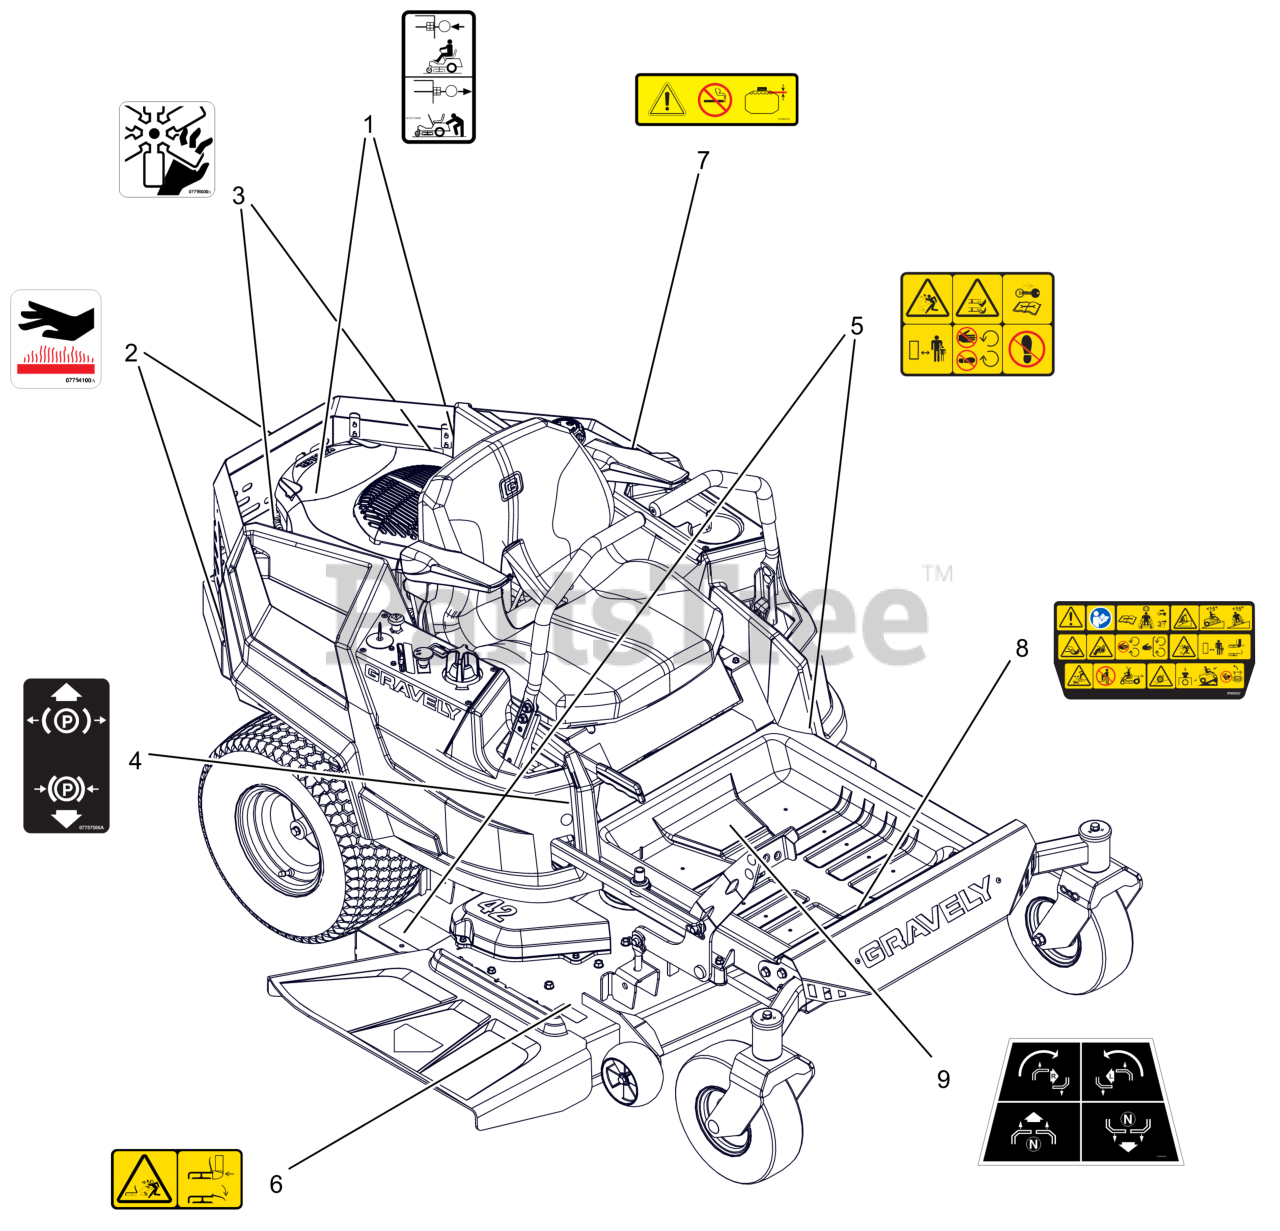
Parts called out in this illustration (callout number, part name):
1	DECAL, TRANSMISSION DISCONNECT
2	DECAL, HOT SURFACE
3	DECAL, DANGER FAN
4	DECAL, PARKING BRAKE LEVER
5	DECAL, SAFETY - MOWER DECK
6	DECAL, SAFETY - DECK GUARDING
7	DECAL-FUEL, WARNING
8	DECAL, MAIN SAFETY
9	DECAL, STEERING
